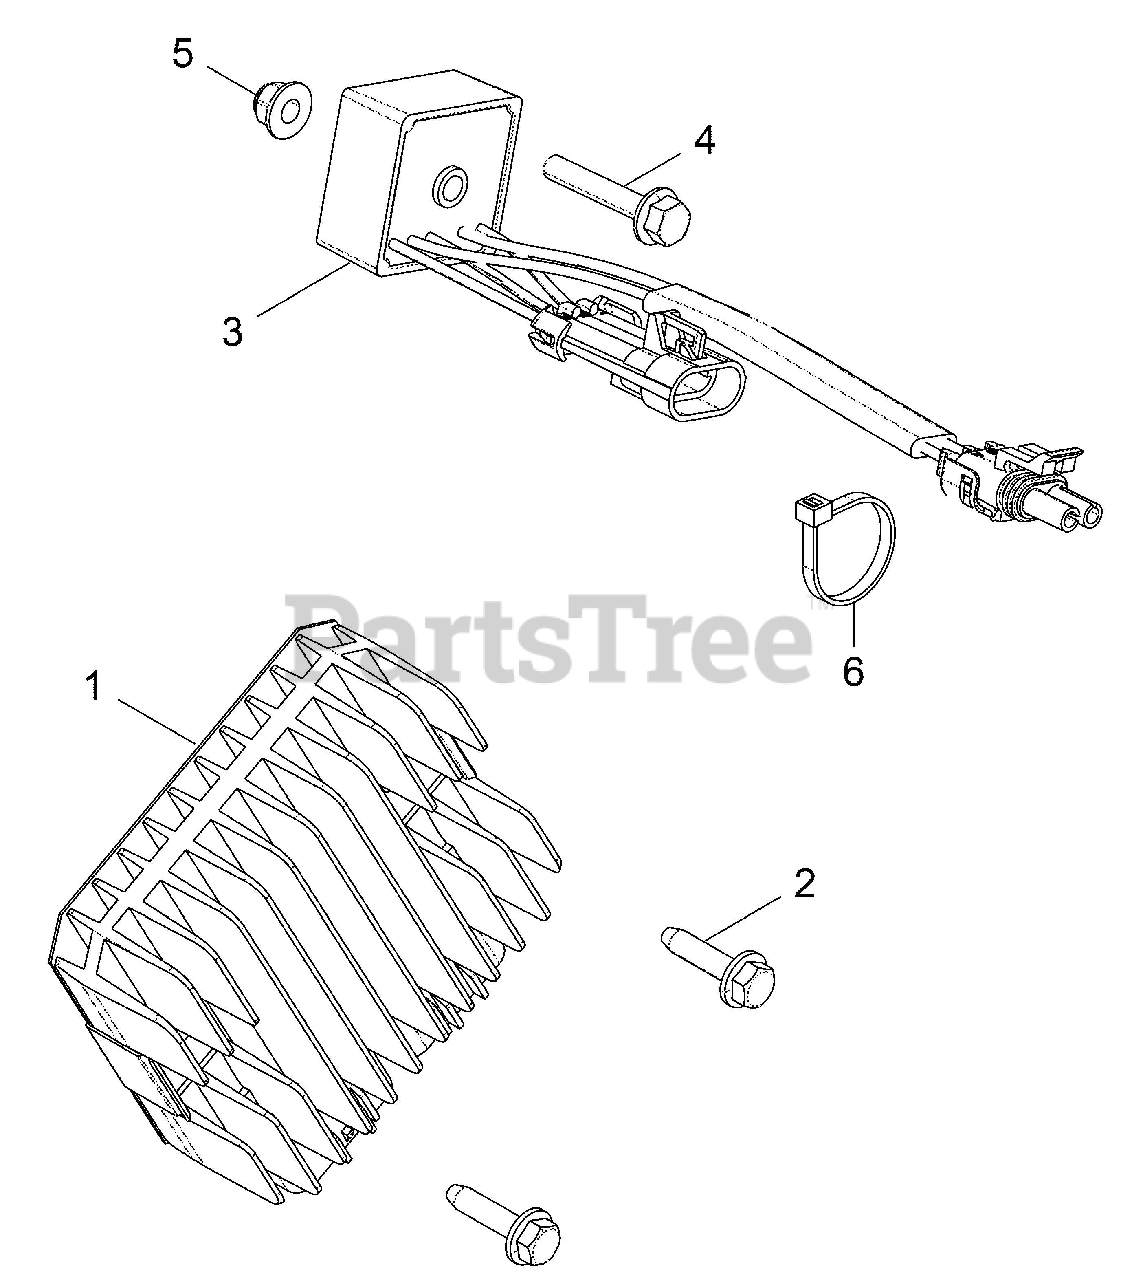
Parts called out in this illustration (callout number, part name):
1	REGULATOR-3PH,50A,SERIES,HISPD
2	SCR-TFHFL-M6X1.0X25,ZOD
3	RELAY, SOLID STATE,9A,LONG LD
4	BOLT-M6X1.0X35,HXFLG/SH-OLV D
5	NUT-M6X1.0,FLG-NYLOC-OLIVE D
6	CABLE TIE (10)
